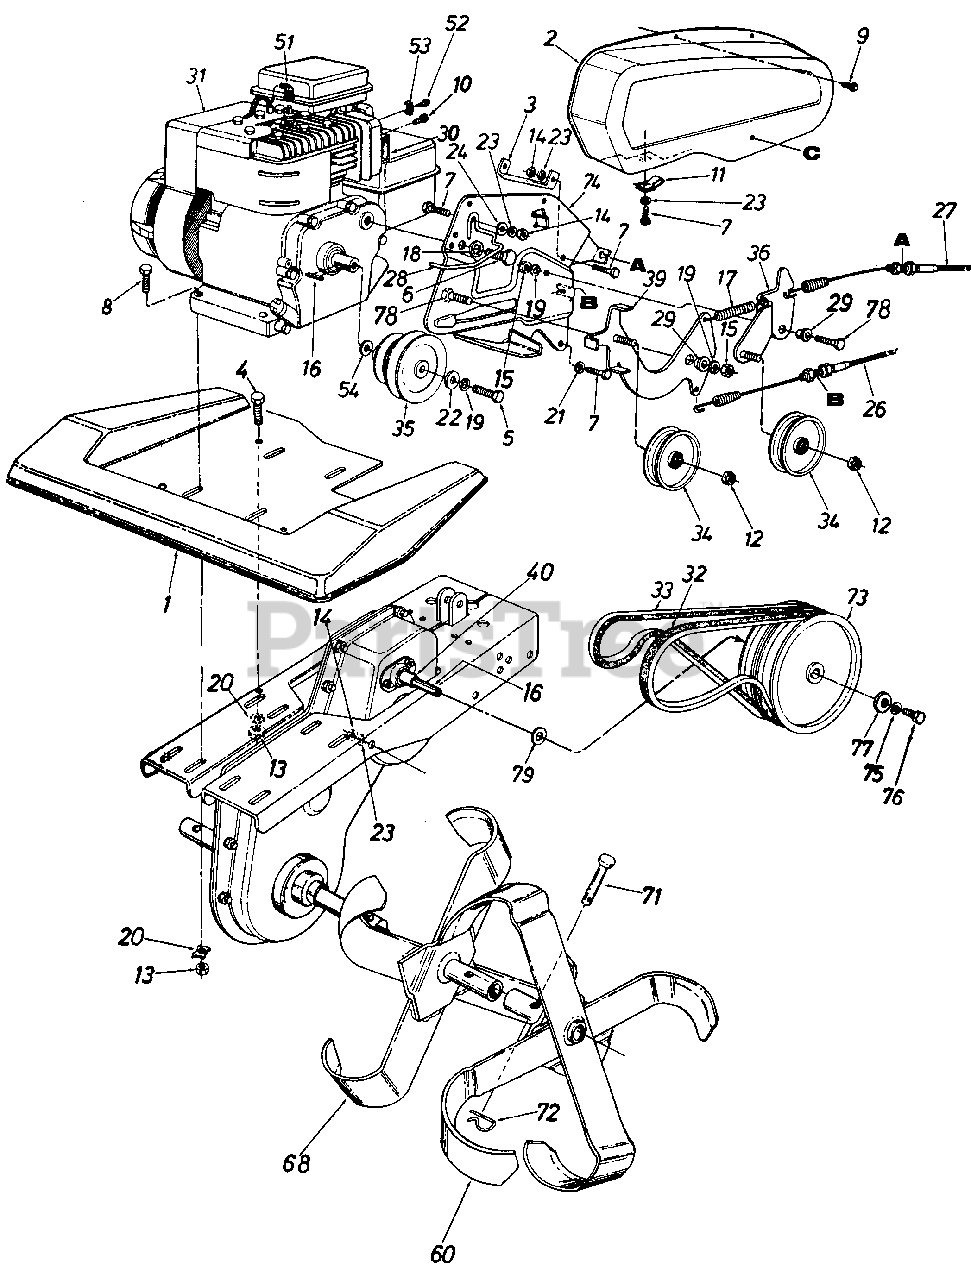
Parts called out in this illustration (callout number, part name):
4	SCREW-HEX 5/16-18 X .75
5	SCREW 3/8-24X1.25 GR5
6	SCREW-HEX 5/16-24 X .62
7	SCREW-HEX 1/4-20 X .75
8	SCREW-HEX 5/16-18 X 1.50
9	SCREW-HEX WASH SF TAPP
10	SCREW-HEX WASH HD 10-32X.38
11	NUT-SPEED-1/4-20
12	NUT-HEX CENTER JAM 3/8-24
13	NUT-HEX 5/16-18
14	NUT-HEX 1/4-20
15	NUT-HEX CENTER L-3/8-16
16	KEY-SQ 3/16X1.50
17	SPRING-EXTENSION
18	WASHER-LOCK-5/16
19	WASHER-LOCK-3/8
20	WASHER-SPEC L 5/16 X .88 OD
21	WASHER-SPRING.270 ID X.51 OD X.030
22	WASHER-FL-.385 X 1.00 X .135
23	LOCK WASHER 1/4 DIA
24	WASHER-FL
26	CABLE-CLUTCH CONTROL
27	CABLE-CLUTCH CONTROL
28	ROD-BELT GUARD
29	SPACER-SHLD
30	DEFLECTOR-MUFFLER
32	BELT-V 1/2 X 37 SPECIAL
33	BELT-V 1/2 X 41
34	PULLEY-ENGINE
35	PULLEY-ENGINE
40	SPACER-.635 ID X .88 OD X 1.03
51	INSULATOR-SPARK PLUG
52	SCREW-HEX SEMS #10-32
53	CLAMP-CASING
54	WASHER-FL
68	TINE ASSY-INNER-LH
71	PIN-CLEVIS
72	PIN-COTTER
74	PLATE-CLUTCH MTG
75	WASHER-LOCK-5/16
76	SCREW-HEX 5/16-18 X 10 SPEC
77	WASHER-FL-.312 X 1.125 X .125
78	BOLT-3/8 NF X 1"GR5
79	WASHER-FL-.640ID X 1.24OD X .06HDN
